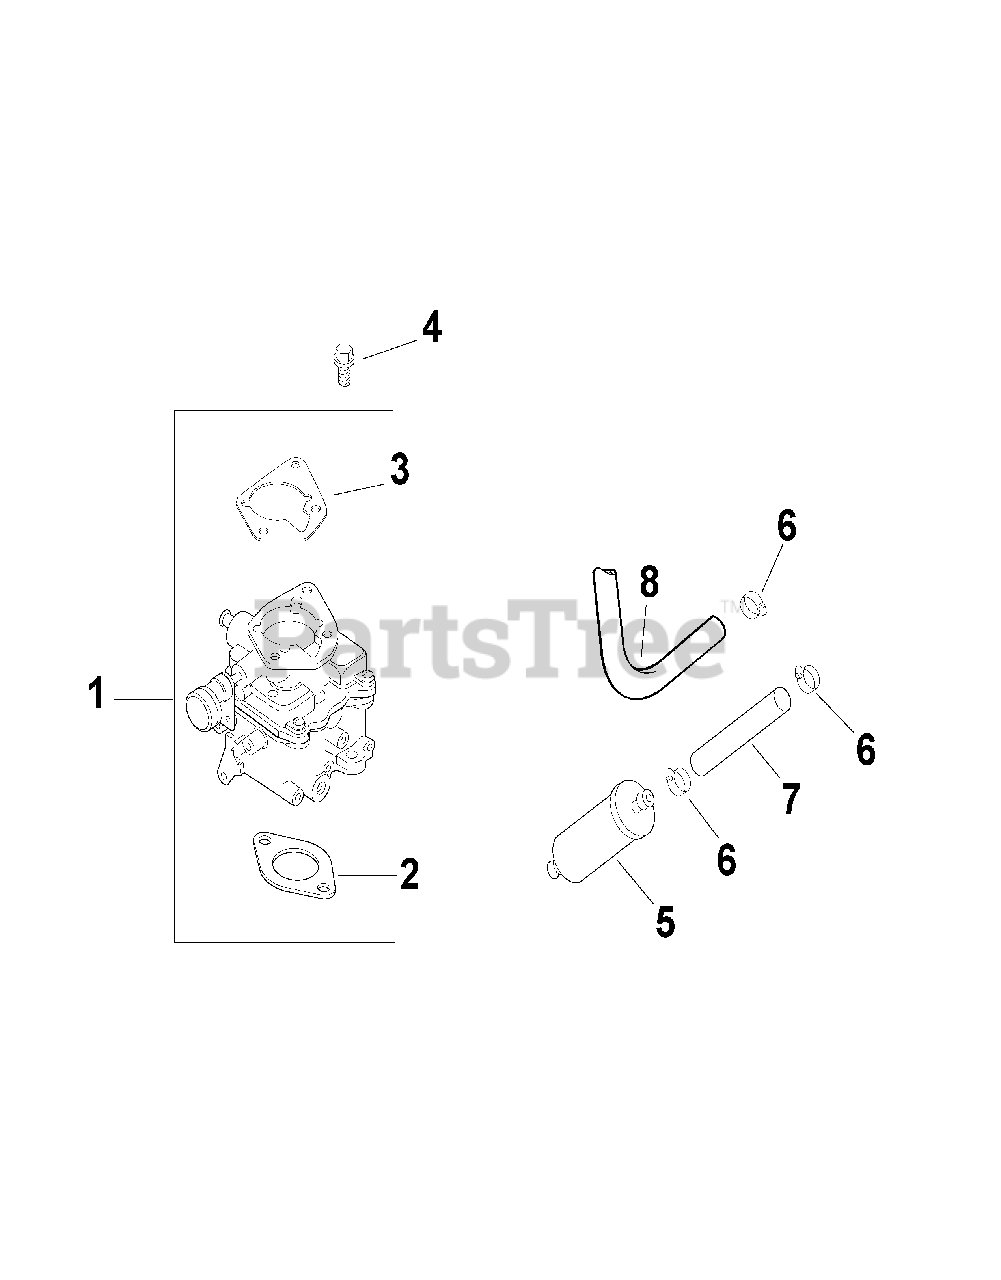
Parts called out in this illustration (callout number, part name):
1	Kit, carburetor w/gasket (Includes 2,3)
2	Gasket, air cleaner base
3	Gasket, carburetor
4	Screw, hex flange M6x1 0x30 (2)
5	Filter, fuel
6	Clamp, hose (4)
7	Line, fuel 21" (carb to filter)
8	Line, fuel 11" (carb to pump)
